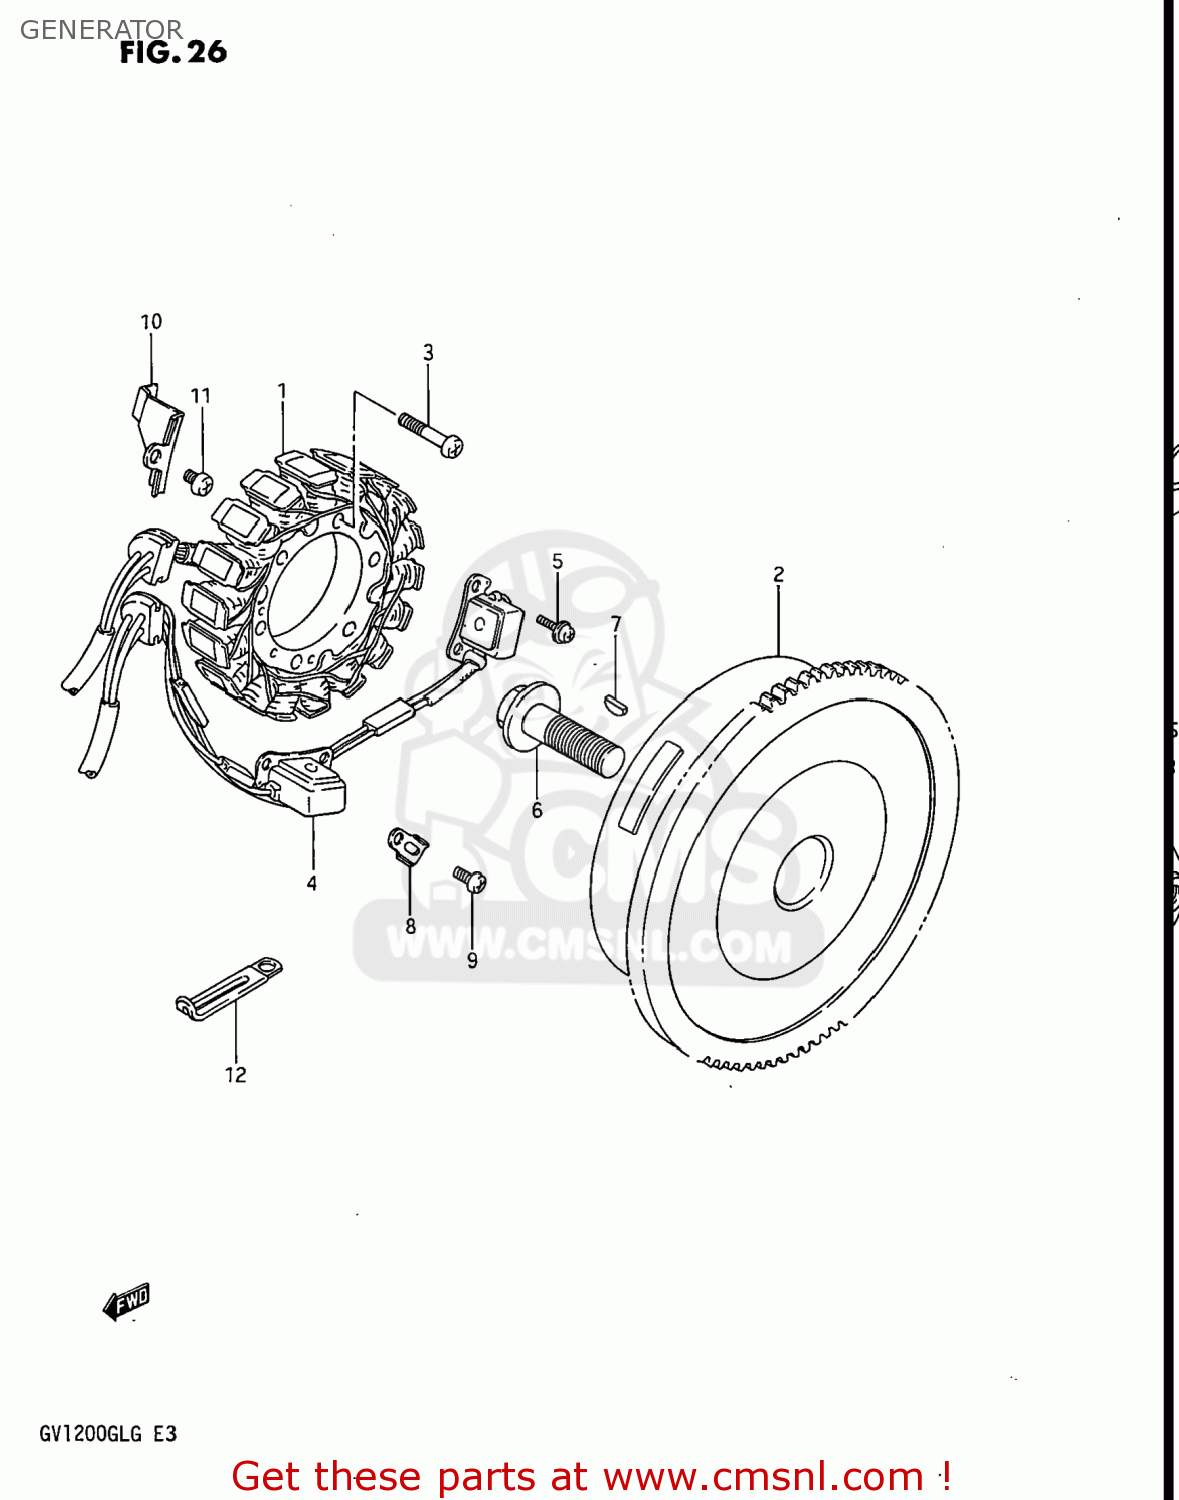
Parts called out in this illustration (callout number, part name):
1	STATOR ASSEMBLY,AC
2	ROTOR ASSEMBLY
3	SCREW 6X30
4	SENSOR ASSEMBLY,TIMING
5	SCREW
6	BOLT(14X43)
7	KEY 4MM
8	CLAMP,GENERATOR LEAD WIRE
9	SCREW
11	SCREW
12	CLAMP
